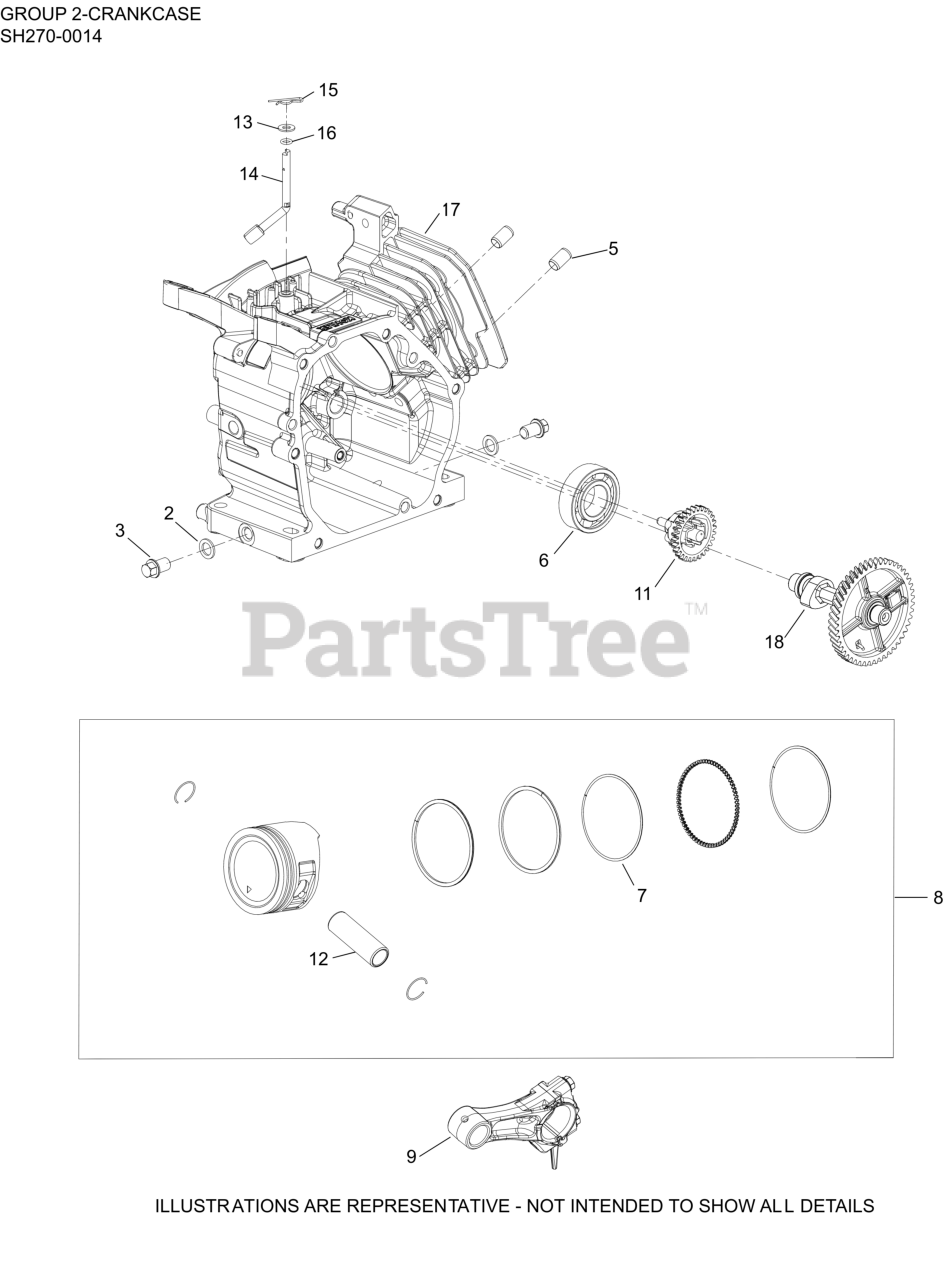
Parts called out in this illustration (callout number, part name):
2	WASHER, DRAIN PLUG
3	KIT, DRAIN PLUG
5	DOWEL, CYLINDER HEAD
6	BEARING, BALL
8	KIT, PISTON (STD)
9	ROD, CONNECTING ASSEMBLY
11	GOVERNOR ASSEMBLY
12	PIN, PISTON
13	WASHER, FLAT (DIA 13mm O.D.)
14	SHAFT, GOVERNOR CROSS
15	CLIP, GOVERNOR SHAFT
17	CRANKCASE
18	CAMSHAFT, ASSEMBLY
